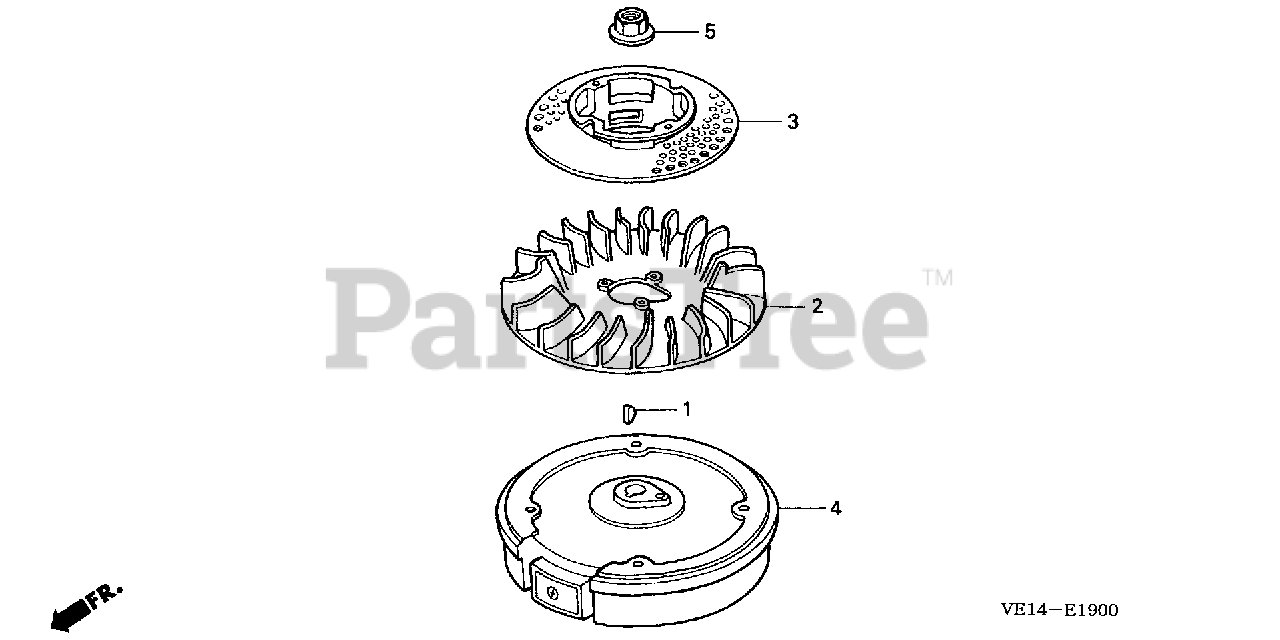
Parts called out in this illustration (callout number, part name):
1	KEY, SPECIAL WOODRUFF (25X18)
2	FAN, COOLING
3	PULLEY, STARTER
5	NUT, SPECIAL (14MM)
